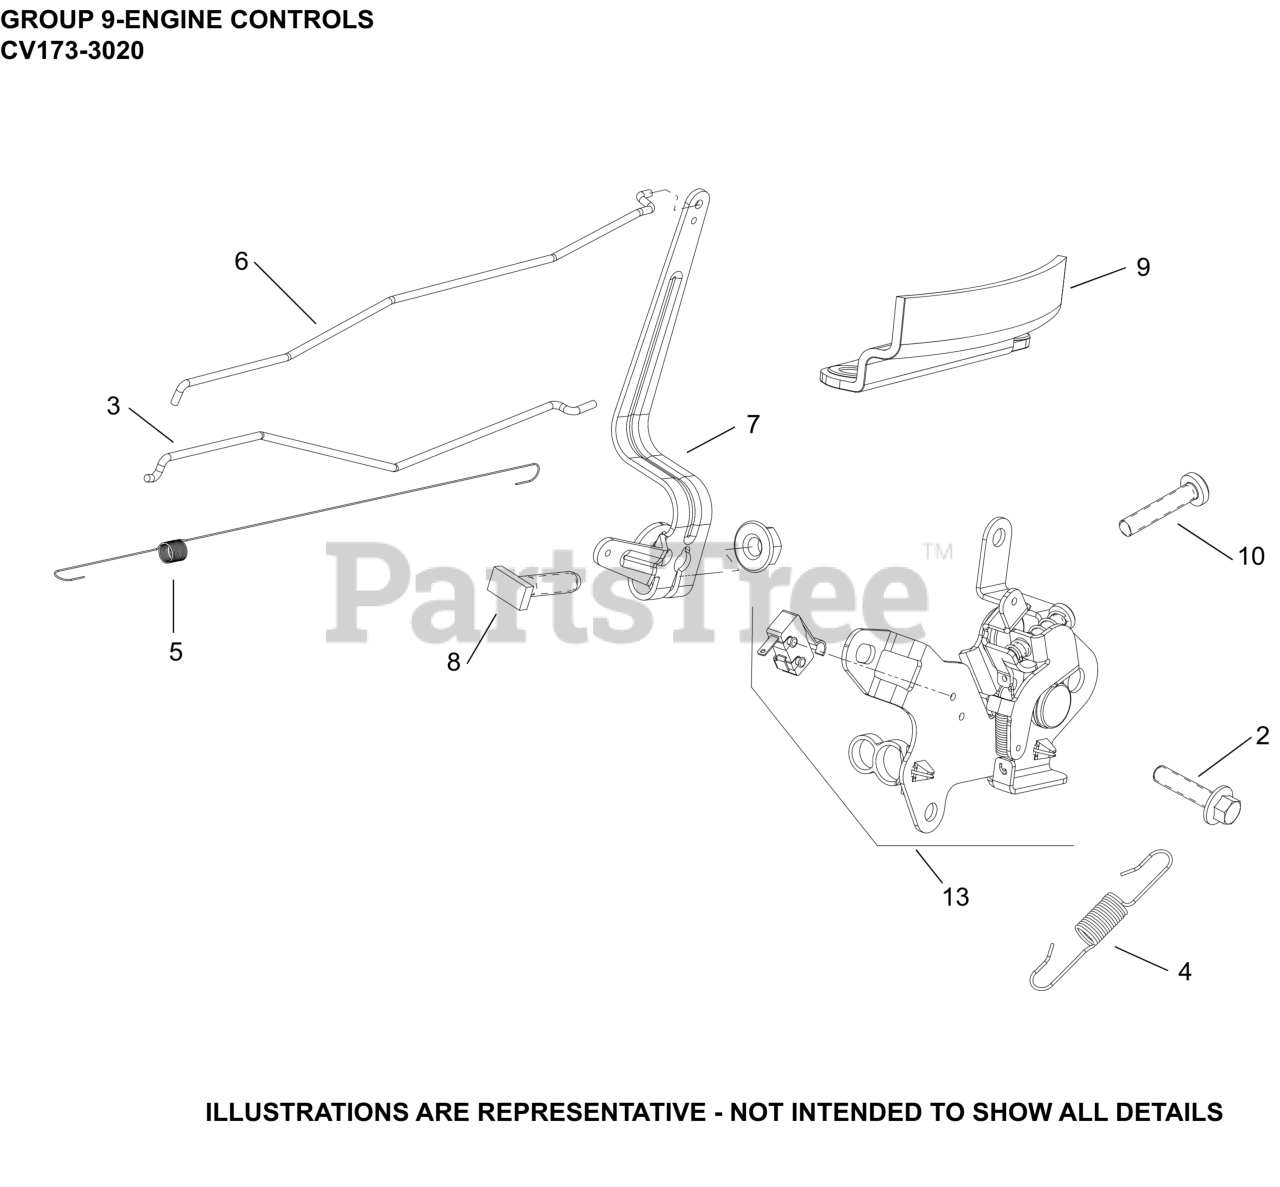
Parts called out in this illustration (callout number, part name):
2	SCREW, (M5) HEX FLANGE
3	LINKAGE, CHOKE
4	SPRING, GOV (2800-3300 RPM)
5	SPRING, LINKAGE
6	LINKAGE, GOVERNOR
7	LEVER, GOVERNOR
8	SCREW, RECTANGLE HEAD (M6)
9	GUARD, FINGER
10	SCREW, SPEED ADJUSTING
13	CONTROL ASSEMBLY, REMOTE VARIABLE SPEED
